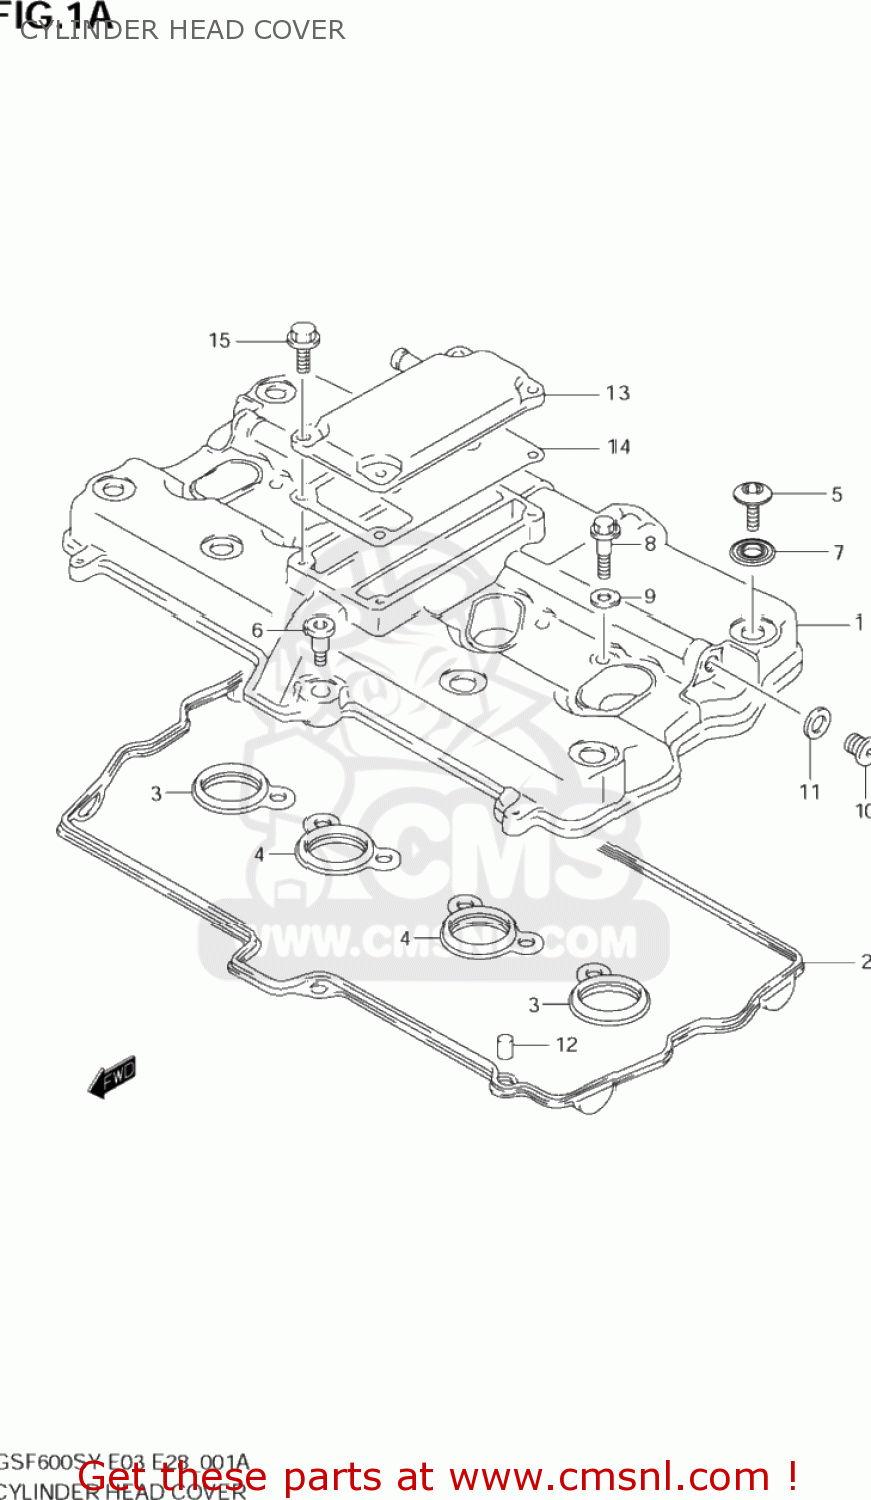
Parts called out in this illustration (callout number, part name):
1	COVER,CYLINDER HEAD
2	GASKET,CYLINDER HEAD COVER (NAS)
3	GASKET,HEAD COVER NO.2 (NAS)
4	GASKET,HEAD COVER NO.3 (NAS)
5	BOLT(7X17.5)
6	BOLT(7X31)
7	WASHER(10.6X25.5X2.3)
8	BOLT,HEAD COVER UNION(8X35)
9	GASKET(8.2X16X1) (NAS)
10	PLUG(L:12)
11	GASKET(12.1X16.2X3.7) (NAS)
12	PIN
13	COVER,BREATHER
14	GASKET,BREATHER COVER
15	BOLT
